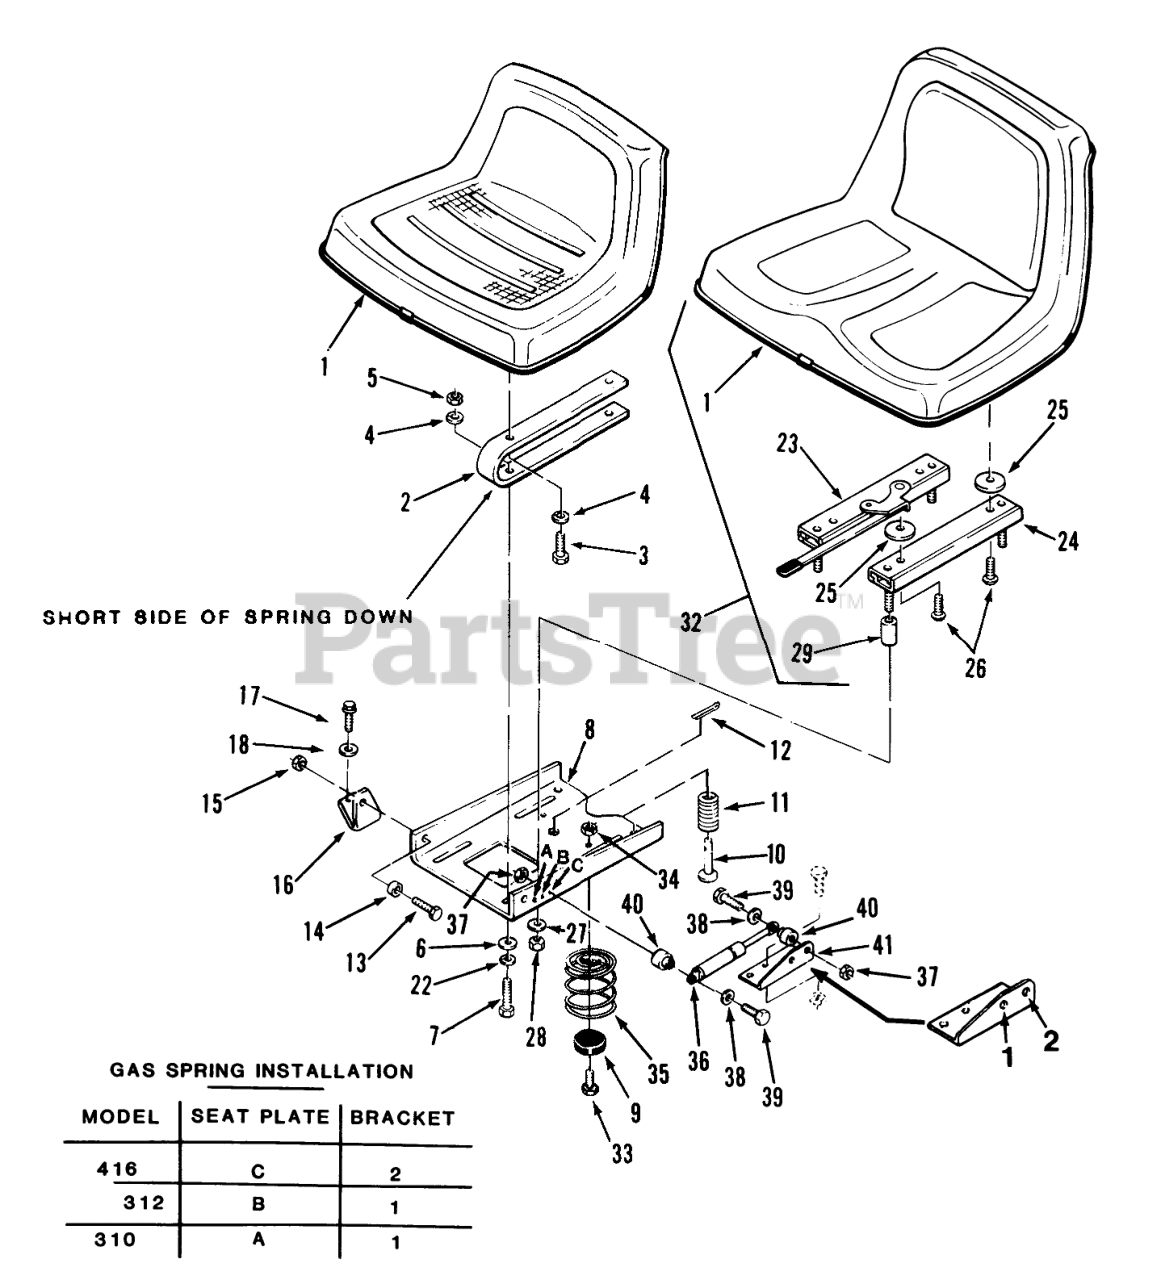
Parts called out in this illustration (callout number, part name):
6	WASHER 5/16 SAE
9	BUMPER
11	SPRING-SEAT SWITCH
14	BUSHING
16	BRACKET-PIVOT R.H *B (NS)
18	WASHER 5/16 SAE
25	SPACER-NYLON
36	GAS SPRING
40	SPACER
41	BRACKET-CYLINDER *R
